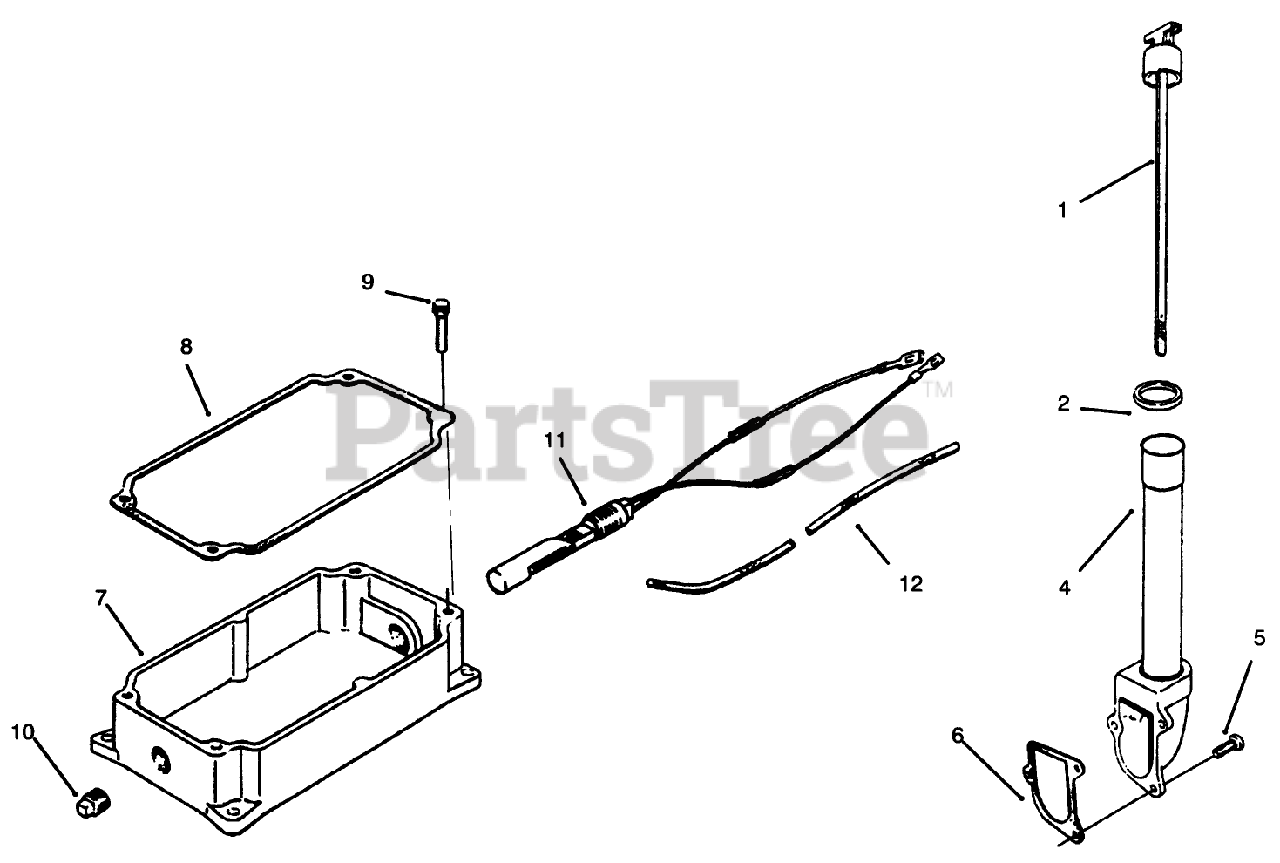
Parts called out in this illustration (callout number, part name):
1	Dipstick
2	O-Ring
4	Adapter-Oil Fill
5	Screw
6	Gasket
7	Pan-Oil
8	Gasket
9	Screw
10	Plug
11	Kit-Float Switch 12hp
12	Sleeve
